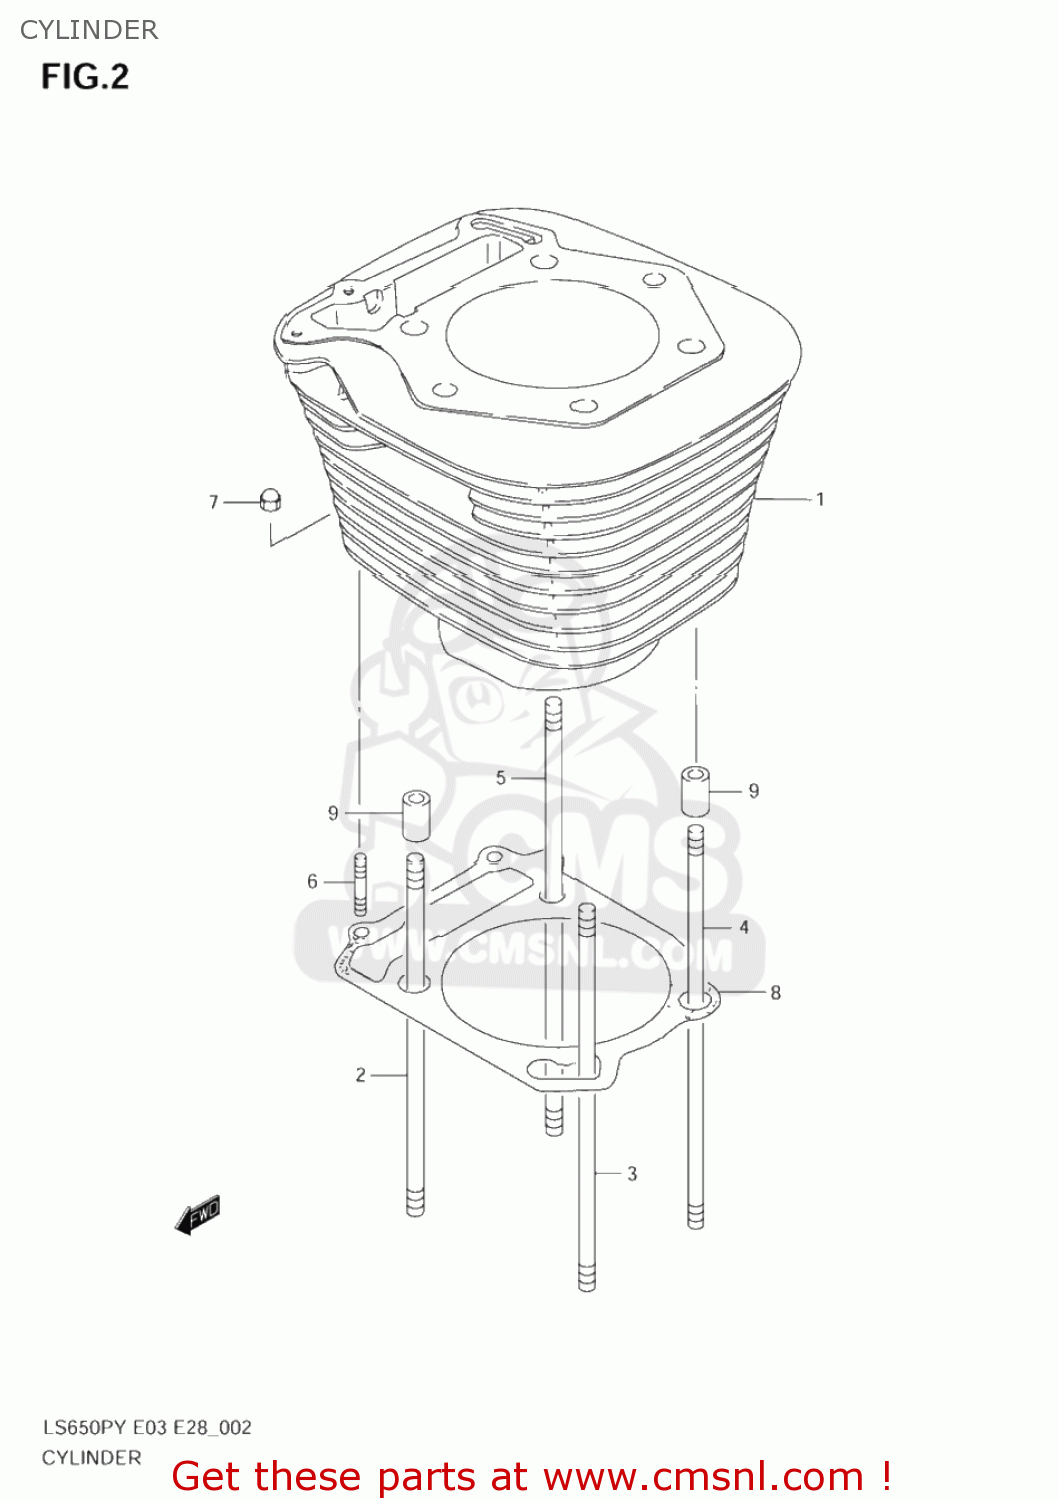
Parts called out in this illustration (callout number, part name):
1	CYLINDER
2	BOLT,STUD
3	BOLT,STUD
4	BOLT,STUD
5	BOLT,STUD
6	STUD 6X20
7	NUT
8	GASKET,CYLINDER (NAS)
9	PIN
